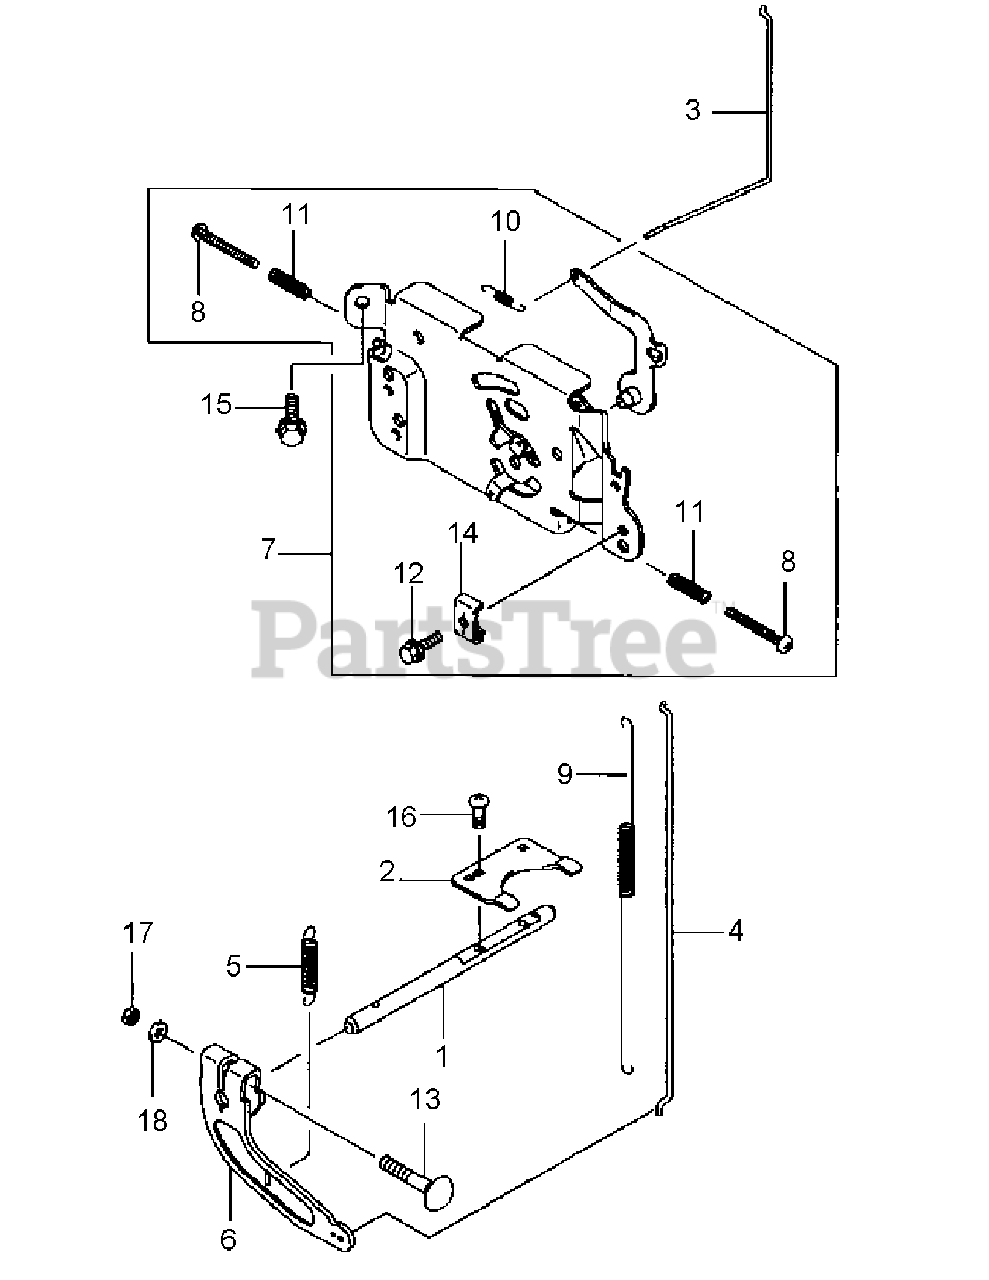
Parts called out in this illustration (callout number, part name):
5	GOVERNOR SPRING
7	CONTROL PANEL
10	SPRING
13	BOLT, 6x35
15	FLANGED BOLT
18	PLAIN WASHER
